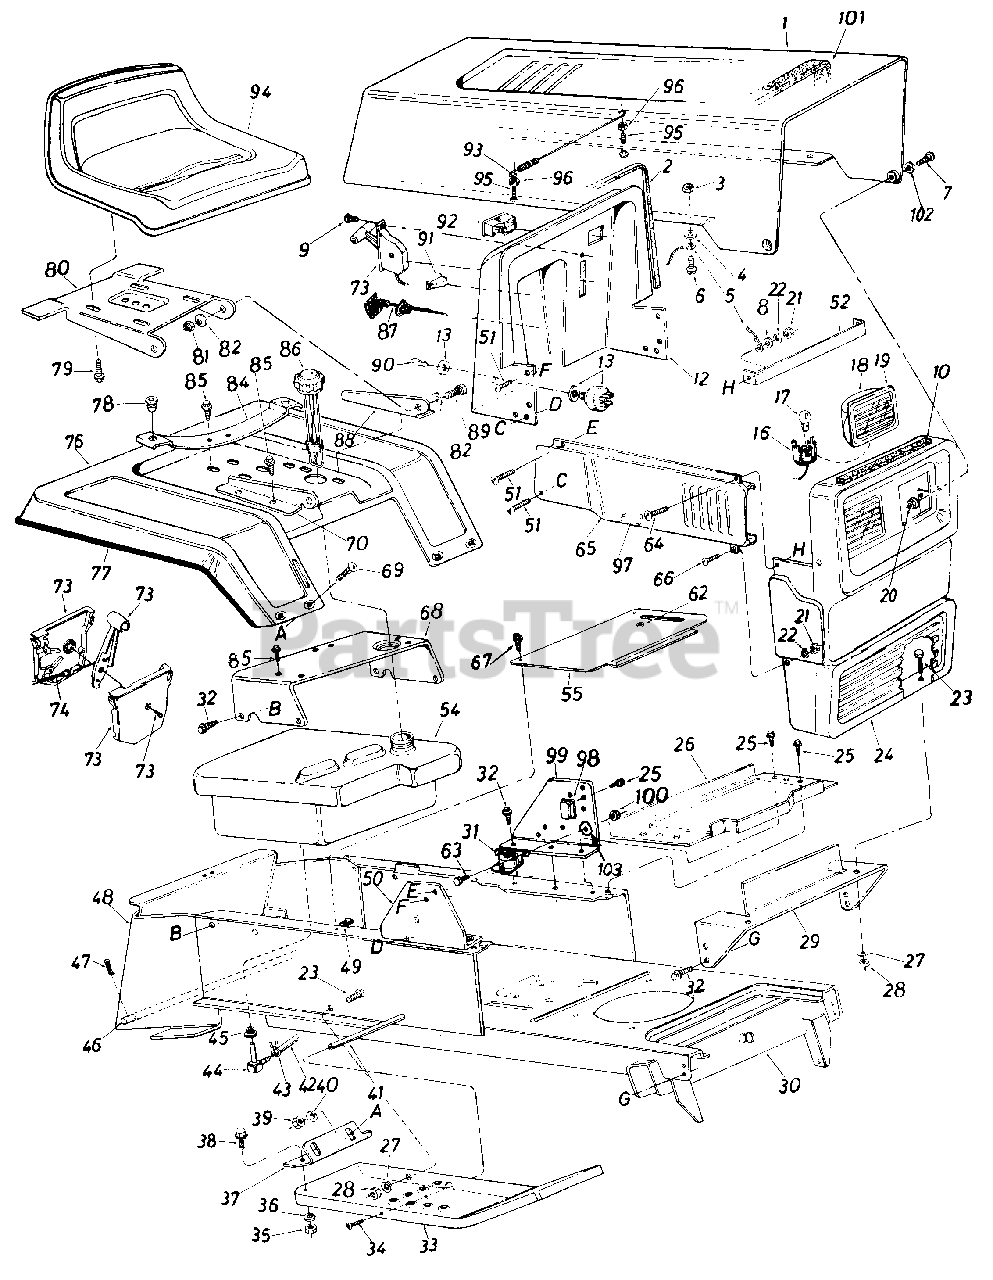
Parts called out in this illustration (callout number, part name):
1	Hood
2	Vinyl Molding Strip-29"
3	Hex Sems Nut #10-24 Thd.
4	Fl-Wash. .20" I.D. x .41" O.D.
5	Hood Stop
6	Truss Hd. Mach. Scr. #10-24 x.50" Lg.*
7	Shld. Bolt .375 Dia. x .125
8	Fl-Wash. 1/4" I.D.*
10	Foam Strip 3/8" x 1" x 14"
12	Dash Ass'y.
13	Ignition Switch
16	Socket
17	Lamp
18	Headlight Housing
19	Lens
20	L-Nut 1/4-28 Thd.
21	Hex Nut 1/4-20 Thd.*
22	L-Wash. 1/4" I.D.*
23	Hex Bolt 5/16-18 x .75" Lg.*
24	Grille (With Headlights)
25	Hex Wash. Hd. AB-Tap Scr. 1/4 x.50" Lg.
26	Battery Plate
27	L-Wash. 5/16" I.D.*
28	Hex Nut 5/16-18 Thd.*
29	Grille Mounting Bracket
30	Lower Frame Ass'y.
31	Solenoid
32	Hex Thd. Rolling Scr. 5/16-24 x .75" Lg.
33	Running Board-R.H.
34	Truss Mach. Scr. 5/16-18 x .75" Lg.*
35	Hex Nut 5/16-18 Thd.*
36	Bell-Wash..34" I.D.
39	Hex Nut 1/4-20 Thd.*
40	L-Wash. 1/4" I.D.*
41	Running Board Rod
42	Fuel Line 44" Lg.
43	Hose Clamp 3/8"
44	90ø Elbow
45	Bushing
46	Hitch Rod
47	Internal Cotter Pin
48	Hitch Plate
49	Speed Nut
50	Dash Support Brkt.-R.H.
51	Hex Wash Hd. Tap Scr. 1/4 x .75" Lg.
52	Tie Strap-Grille Side Panel
54	Fuel Tank
55	Transmission Cover Ass'y.
62	Snap Bushing
63	Hex Bolt 1/4-20 x .50" Lg.
64	Truss Hd. Scr. 1/4-20 x .75" Lg.
65	Side Panel-R.H.
66	Truss Mach. Scr. 1/4-20 x .50" Lg.
67	Truss Mach. B-Tap Scr. #10 x.50" Lg.
68	Seat Mounting Channel
69	Carriage Bolt 1/4-20 x .50" Lg.*
70	Seat Bracket-R.H.
73	Throttle Control Box Ass'y.
74	Throttle Control Wire
78	Grommet
79	Hex Wash. Hd. AB-Tap Scr. 3/8 x .75" Lg.
80	Seat Pivot Bracket
81	Hex Cent. L-Nut 5/16-18 Thd.
82	Belleville Wash. .34" I.D. x .88" O.D.
84	Seat Spring
85	Hex Wash. Hd. Self-Tap Scr. 5/16-18 x .50" Lg.
86	Gas Cap w/Gauge
87	Choke Control Comp.
88	Seat Bracket-L.H.
89	Hex Bolt 5/16-18 x .75" Lg.
90	Ignition Key
91	Light Switch
92	Ammeter
93	Hood Spring
94	Seat Ass'y.
95	Hex Bolt #10-24 x 1.0" Lg.
96	Hex Sems Nut #10-24
97	Rubber Strip 1/2" Sq. x 2-1/2" Lg.
98	Circuit Breaker
99	Dash Support Brkt.-L.H.
100	Hex Sems Nut 1/4-20 Thd.
101	PVC Foam
102	Washer .34" I.D. x .62" O.D.
103	External L-Wash. 1/4" I.D.
